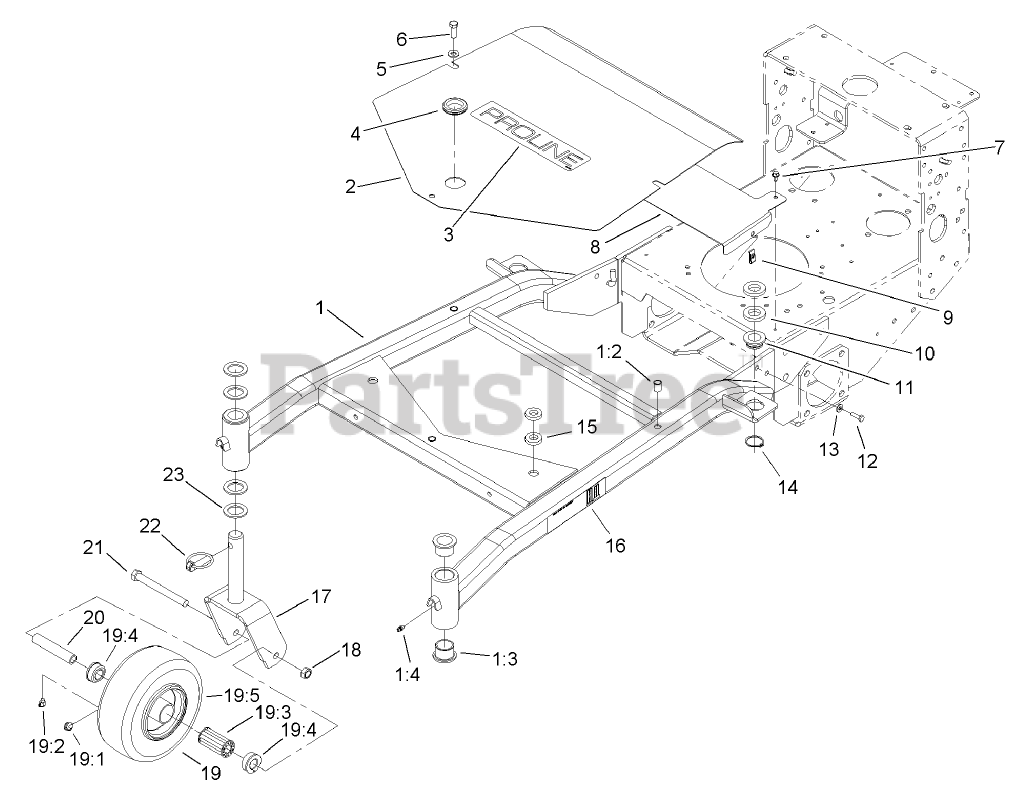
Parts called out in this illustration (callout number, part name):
1	Carrier Frame ASM
1:2	INSERT-NUT
1:3	BUSHING
1:4	FITTING-GREASE
2	COVER-FRAME, CARRIER
4	GROMMET-RUBBER
5	WASHER-FLAT
6	SCREW-HH
7	SCREW
8	Shield-Heat
9	NUT-SPEED
10	SPACER-SUPPORT, DECK
11	BUSHING-DECK
12	SCREW-HH
13	WASHER-FLAT
14	RING-RETAINING
15	SPACER
17	FORK-CASTOR
18	NUT-HEX
19	CASTER WHEEL ASM
19:1	STEM-VALVE
19:2	FITTING-LUBE, 45 DEG
19:3	BEARING
19:4	BEARING-OUTSIDE
19:5	TIRE-TUBELESS
20	BUSHING-SPANNER
21	SCREW-HH
22	PIN-LYNCH
23	WASHER-THRUST
